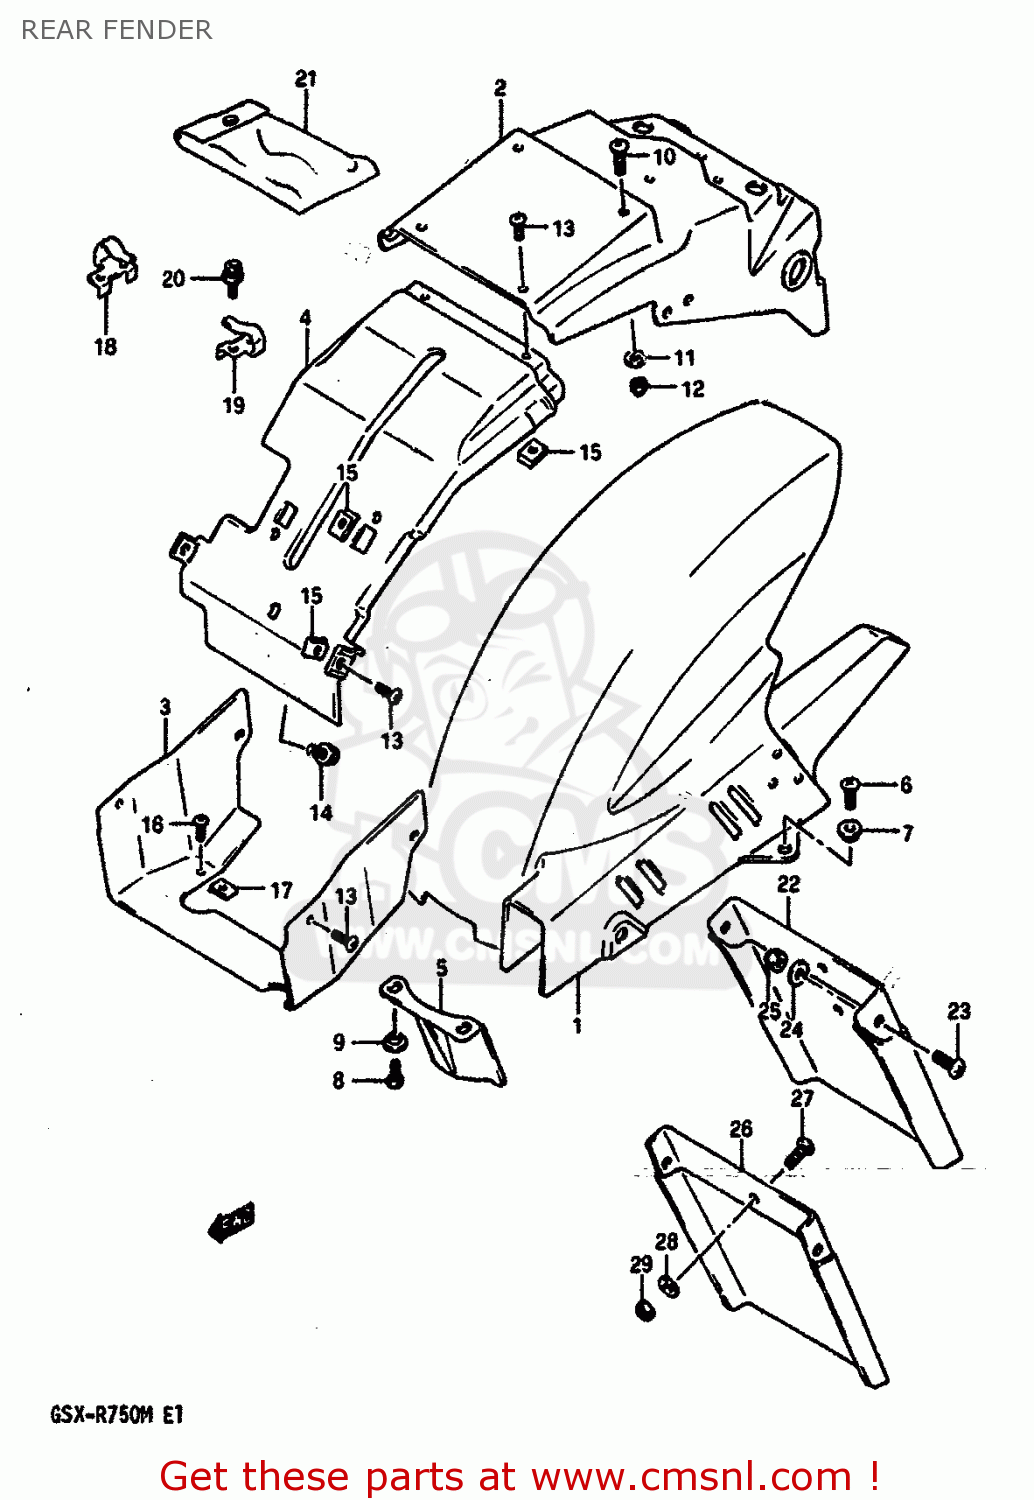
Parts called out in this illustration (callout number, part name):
1	FENDER,RR LWR
2	FENDER,RR UPR
3	FENDER,REAR
4	FENDER,RR UPR FR NO.2
5	GUARD,RR UNIT MUD
6	SCREW
7	WASHER
8	SCREW
9	WASHER,LOCK
10	SCREW
11	WASHER
12	NUT
13	SCREW, FRONT & REAR
14	BOLT
15	NUT,HEADLAMP HOUSING,UPPER
16	SCREW, FRONT & REAR
17	NUT,HEADLAMP HOUSING,UPPER
18	HOLDER,HELMET,R
19	HOLDER,HELMET,L
20	BOLT
21	TOOL ASSY
22	EXTENSION,REAR FENDER
23	SCREW
24	WASHER
25	NUT
26	MUD GUARD
27	SCREW
28	WASHER
29	NUT
